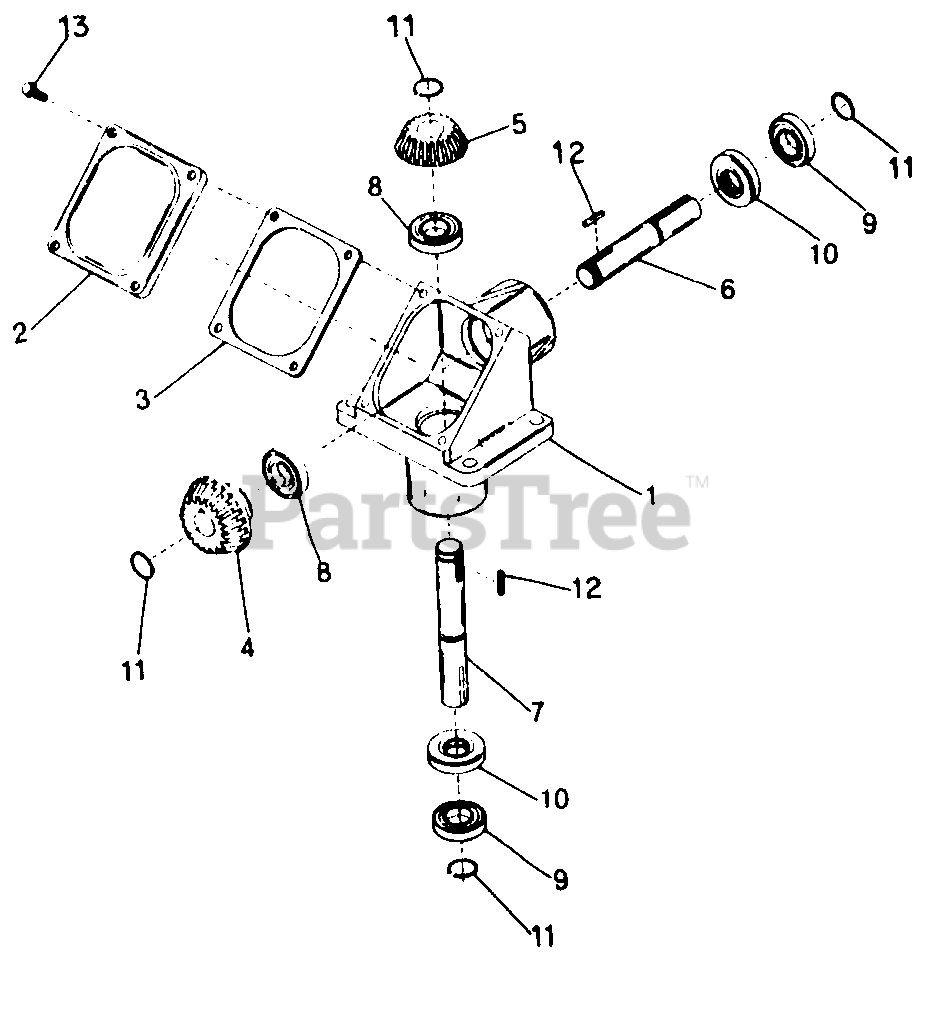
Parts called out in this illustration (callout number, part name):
2	Cover, Gear Box
3	Gasket, Gear Box Cover
4	Gear, Bevel - 30 Tooth
5	Gear, Bevel - 20 Tooth
6	Shaft, Output
7	Shaft, Input
8	Bearing, Ball
9	Bearing, Ball
11	Ring, .693 Ext Ret
12	Key, 3/16 X 11/16 Sq Parallel
13	Screw, 1/4-14 X 1/2 H/Hd Tap
